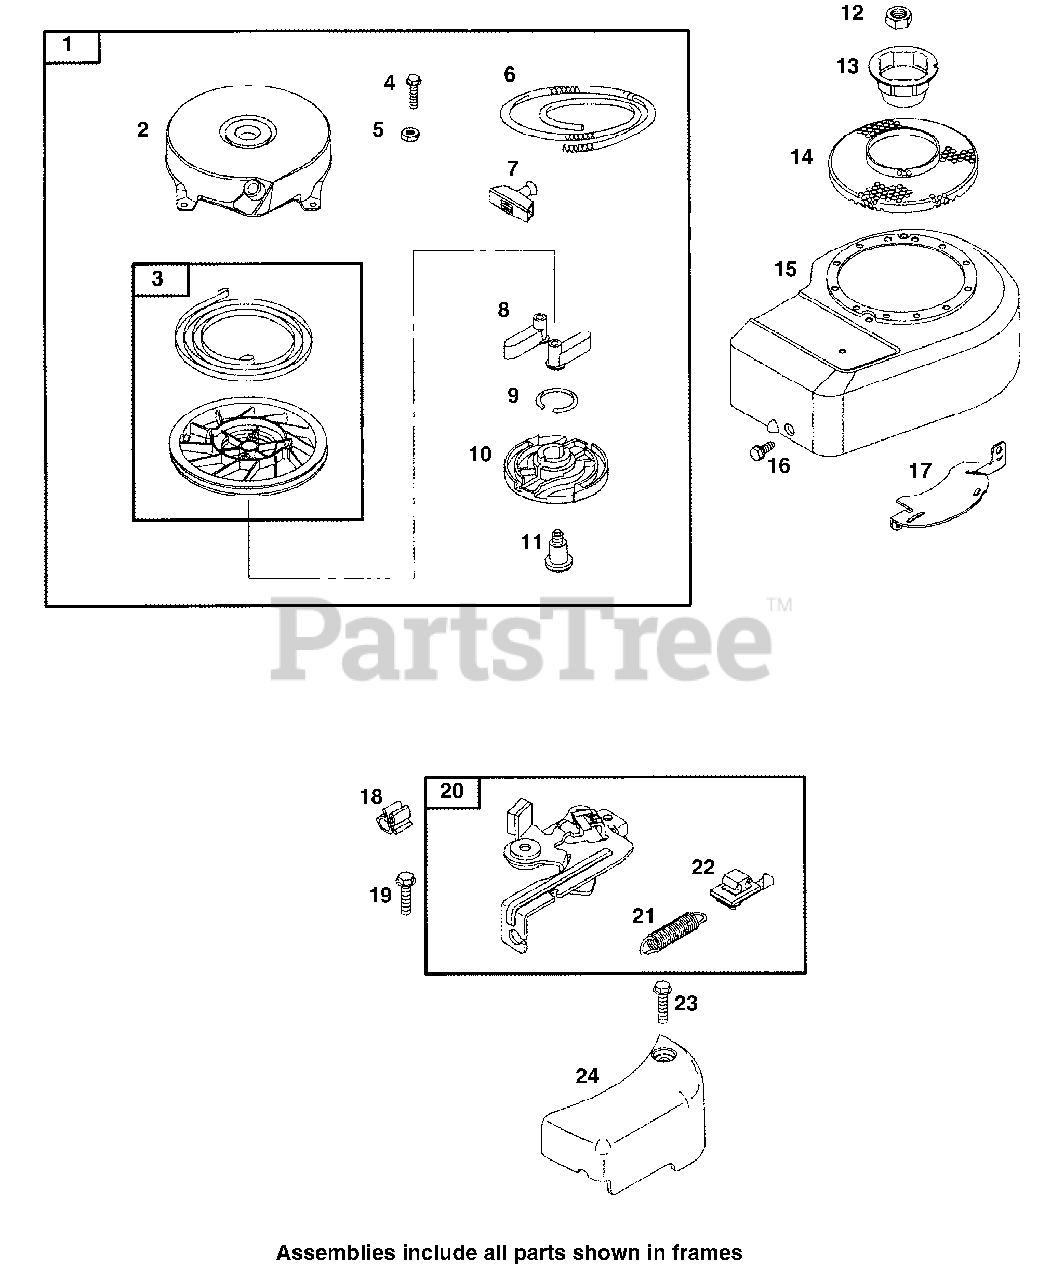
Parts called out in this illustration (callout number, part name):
1	Rewind Starter
2	Rewind Starter Housing
3	Pulley Spring Assembly
4	Hex Screw
5	Hex Nut
6	Starter Rope
7	Starter Rope Grip
8	Rachet Pawl
9	Friction Spring
10	Pawl Friction Plate
11	Shoulder Screw
12	Flywheel Nut
13	Flywheel Cup
14	Rotating Screen
15	Blower Housing
16	Hex Screw
17	Flywheel Guard
19	Hex Screw
20	Brake Bracket
21	Brake Spring
22	Stop Switch
24	Linkage Cover
